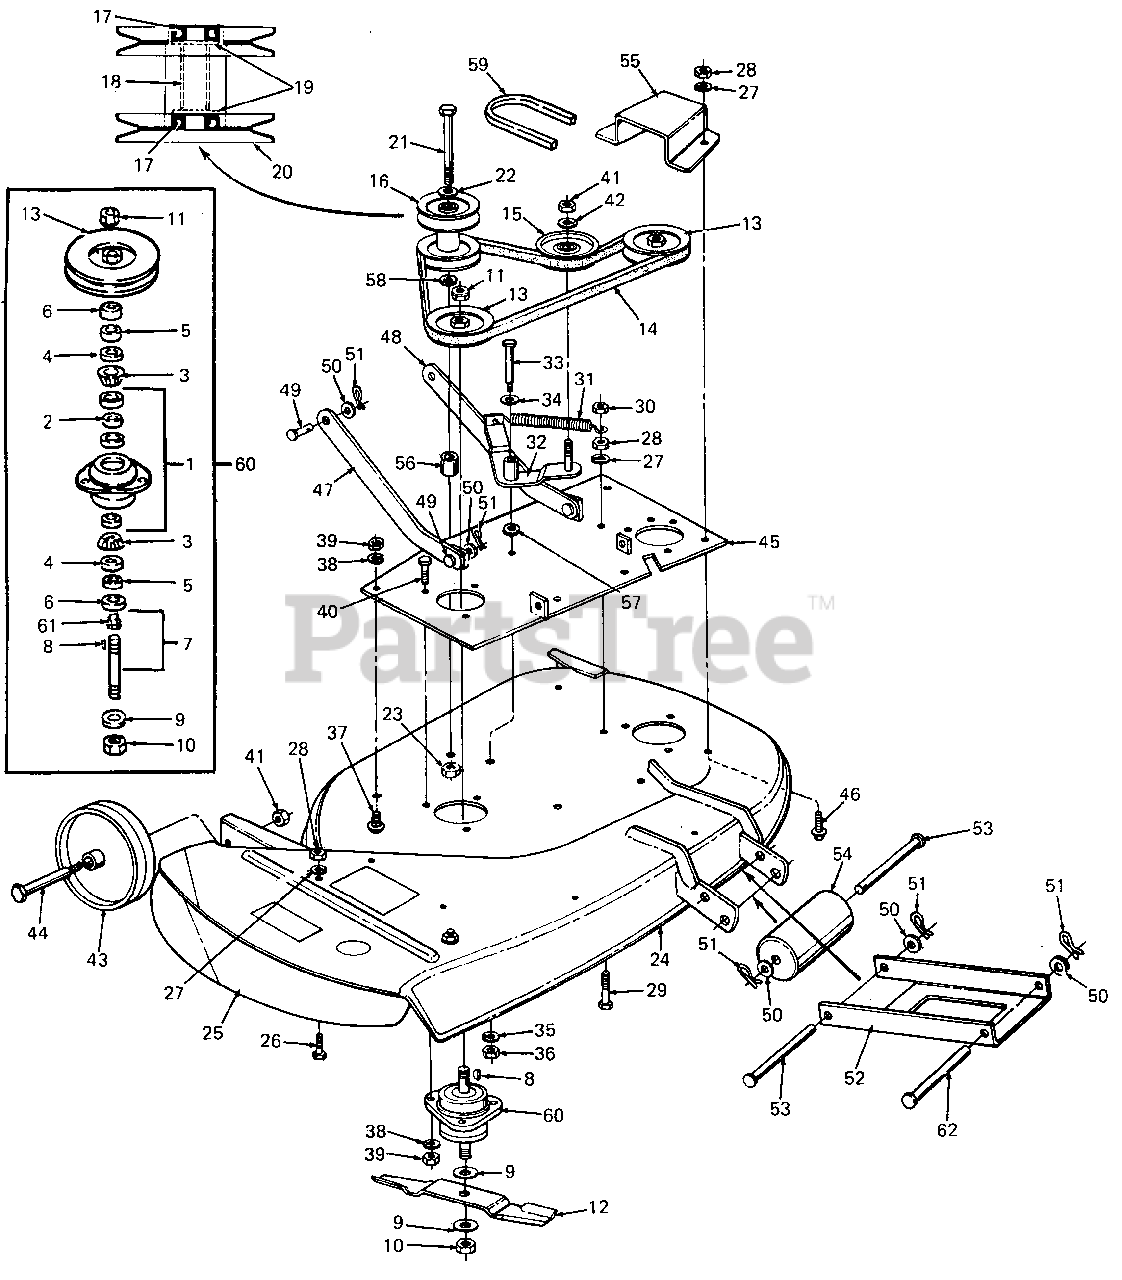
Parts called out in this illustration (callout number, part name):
1	Housing Assy, Spindle w/Cups
2	Spacer, Bearing
3	Bearing, Cone
4	Seal, Oil, 1.25 ID X 1.87 OD X .25
5	Spacer, .755 X 1.25 X .44
6	Cup, Spindle
7	Shaft, Spindle w/Fitting
8	Key, #91 Woodruff, 1/4 X 3/4
9	Washer, .781 X 2.0 X .105
10	Nut, 3/4-16 GR8
11	Nut, Hex Insert Top Lock Jam, 3/4-16
12	Blade, Mower
13	V-Pulley, 4L
14	Belt, Full "V", 1/2 X 60" Lg
15	Pulley, Flat Idler, 3.88 X .38
16	Pulley Assy, Double
17	Bearing, Ball, .62 ID X 1.38 OD X .44 Thk
18	Spacer, Pulley, .64 ID X .81 OD X 2.25 Lg
19	Snap Ring, Internal
20	Pulley, Double
21	Bolt, 5/8-18 X 4.25 GR5
22	Washer, .625 X 1.0 X .06 HDN
23	Nut, Lock, 5/8-18
26	Bolt, 5/16-18 X .75
27	Washer, Lock, 5/16
28	Nut, 5/16-18
29	Bolt, 3/8-16 X 1.5
30	Nut, Lock, 5/16-18 GR5
31	Spring, Extension, .81 OD X 4.75
32	Arm, Idler
33	Bolt, Shoulder, .68 X 1.56 X 7/16-14
34	Washer, .793 X 1.25 X .06 HDN
35	Washer, Lock, 7/16
36	Nut, 7/16-14
37	Bolt, 3/8-16 X .75 CRG
38	Washer, Lock, 3/8
39	Nut, 3/8-16
40	Bolt, 3/8-16 X 1.0
41	Nut, Lock, 3/8-16
42	Washer, .406 X .75 X .063
43	Wheel, Deck, 5.0 Dia
44	Bolt, Shoulder, .498 X 1.53 X 3.8-16
45	Plate, Spindle Mounting
46	Screw, Hex Hd Dog Pt Tapp, 5/16-18 X .75
47	Link, Deck
48	Link Assy, Deck
49	Pin, Clevis, .499 X .78
50	Washer, .510 X 1.0 X .06
51	Pin, Internal Cotter
52	Bracket, Deck Front Support
53	Pin, Clevis, 1/2 Dia X 7.68
54	Roller, Front
55	Cover, Pulley
56	Spacer, .631 X 1.25 X .33
57	Washer, .469 X .88 X .063
58	Bushing, .63 X 1.25 X .33
59	V-Belt, 4L X 59" Lg
60	Spindle Service Kit
61	Fitting, Lube, 3/16
62	Rod, Deck Support
